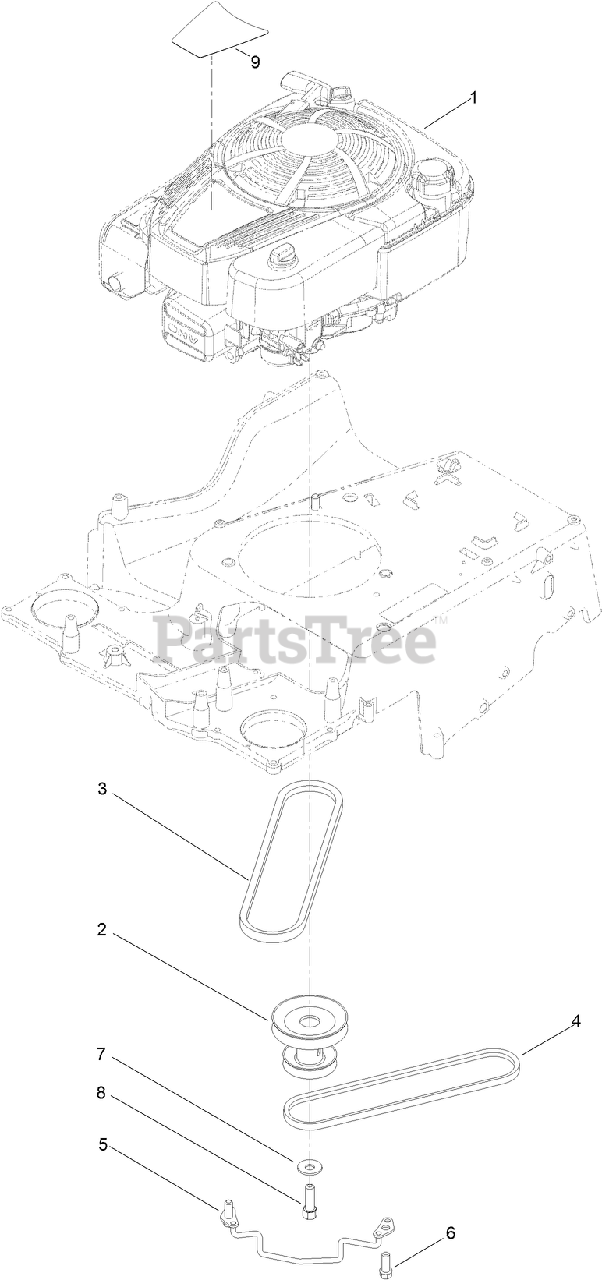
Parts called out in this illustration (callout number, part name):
2	PULLEY-ENGINE
3	V-BELT
4	V-BELT, TRACTION
6	SCREW-TAPTITE
7	WASHER-BELLEVILLE
8	SCREW-HH
9	DECAL-SHROUD
